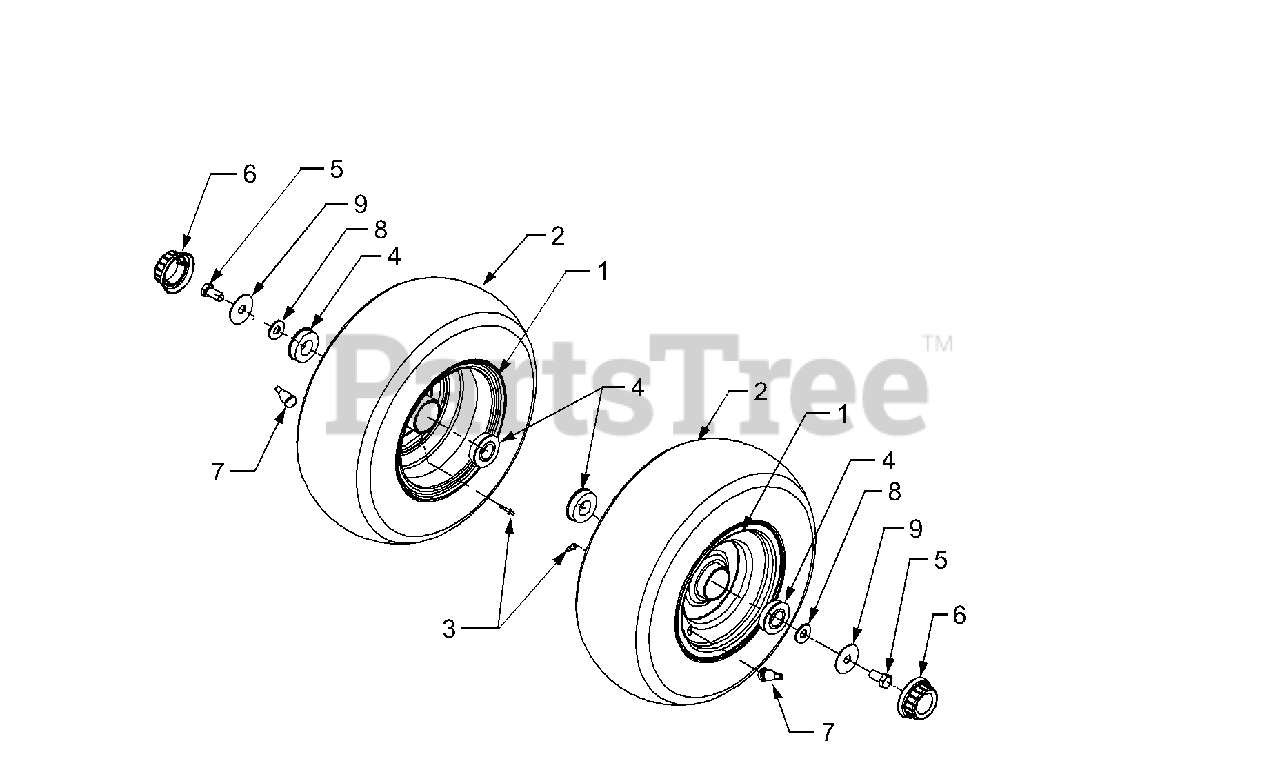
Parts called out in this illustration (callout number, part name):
1	Rim Assembly, Wheel
2	Tire, Turf, 16 x 6.5 x 8.0
3	Lube Fitting
4	Bearing, Ball
5	Screw, Hex Cap, 1/2-13 x 1.0 GR5
6	Hubcap
7	Valve, Tubeless Air
8	Washer, Flat, .531 x 1.25 x .1
9	Washer, Flat, .535 x 1.92 x .060
